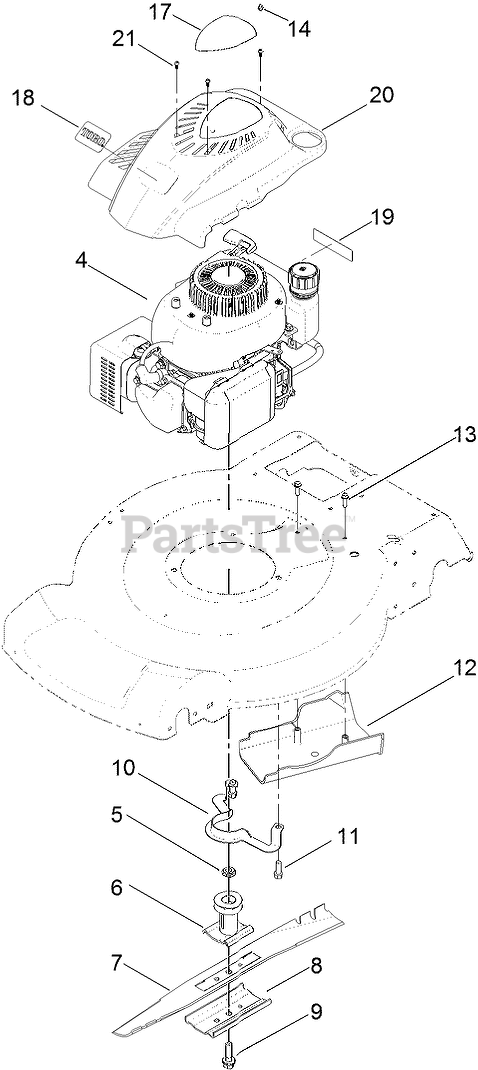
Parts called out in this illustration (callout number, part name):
4	ENGINE-1P65FC
5	Spacer-Driver
6	DRIVER-BLADE
7	BLADE-22 INCH
8	SUPPORT-BLADE
9	BOLT-BLADE
10	Guide-Belt
11	SCREW-TAPTITE
12	COVER-BELT
13	SCREW-HWH
14	STOP-ROPE
17	DECAL-SHROUD
19	DECAL-ARRESTER, SPARK
20	SHROUD
21	SCREW-PPH
